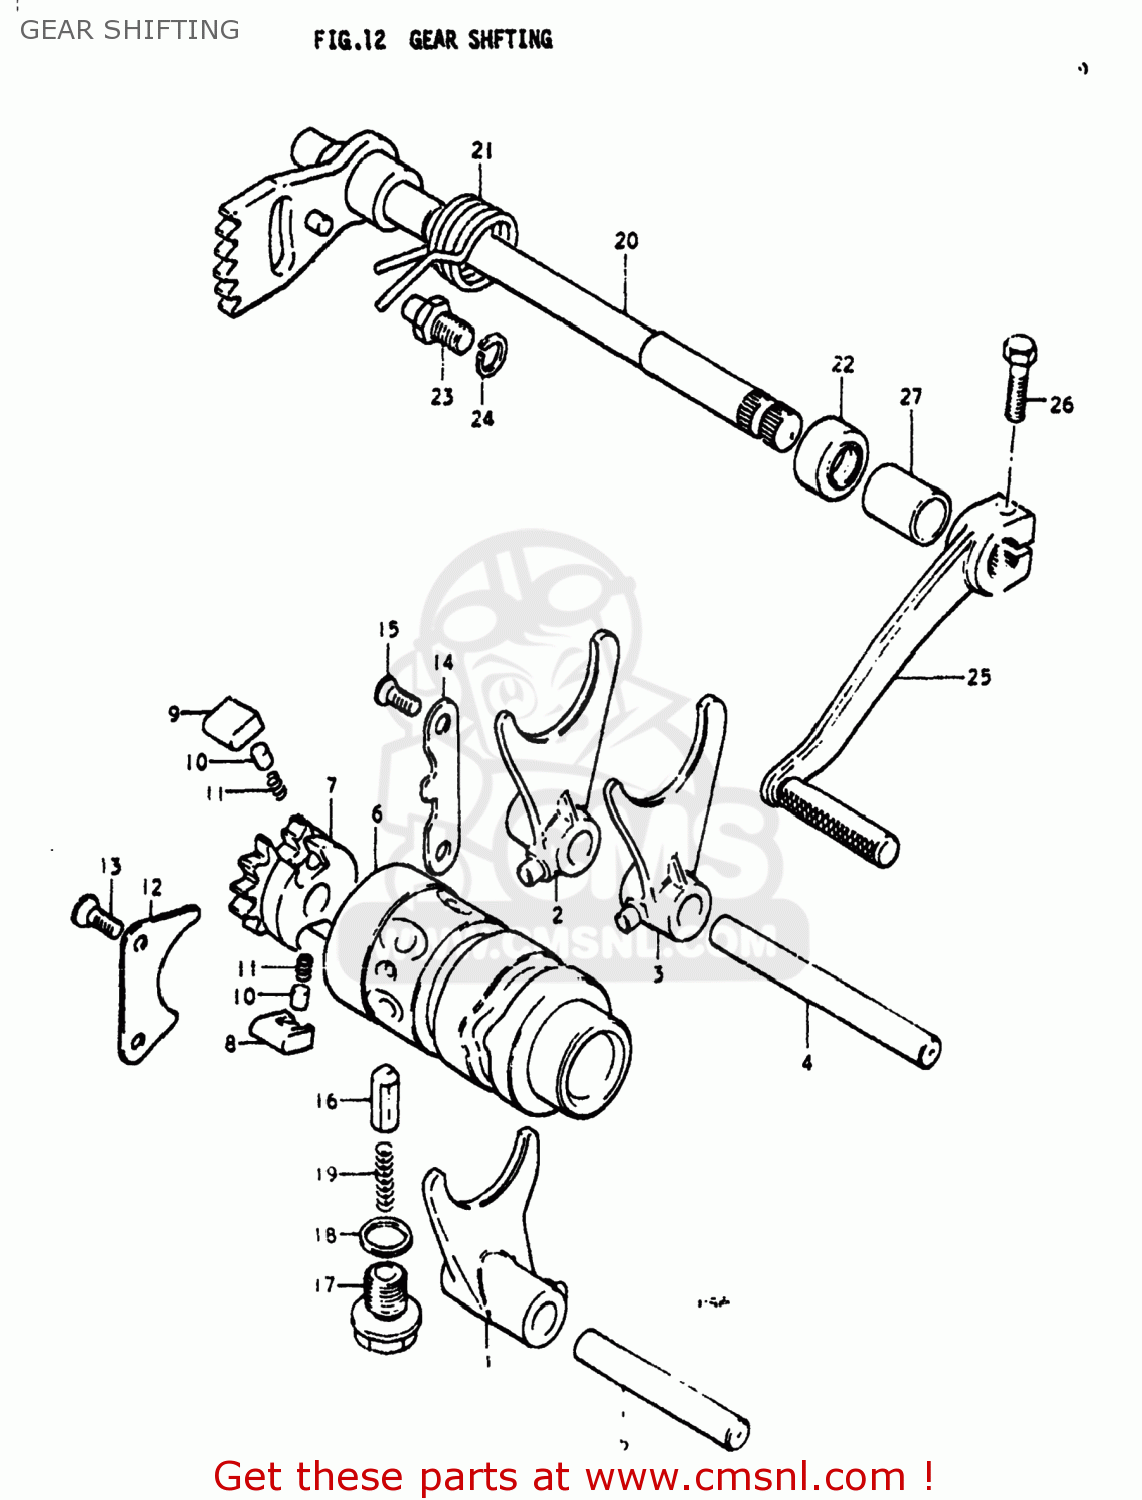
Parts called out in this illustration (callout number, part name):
1	FORK,GEAR SHIFT NO.1
2	FORK,GEAR SHIFT NO.2
3	FORK,GEAR SHIFT NO.3
4	SHAFT,GEAR SHIFT FORK
5	SHAFT,GEAR SHIFT FORK
6	CAM,GEAR SHIFT
7	RETAINER,GEAR SHIFT CAM
8	PAWL,GEAR SHIFT NO.1
9	PAWL,GEAR SHIFT NO.2
10	PIN(5X8)
11	SPRING
12	LIFTER,GEAR SHIFT PAWL
13	SCREW
14	STOPPER,GEAR SHIFT POLE
15	SCREW
16	STOPPER,GEAR SHIFTING
17	BOLT,GEAR SHAFT CAM STOPPER
18	GASKET(14X19.2X2) (NAS)
19	SPRING
20	SHAFT,GEAR SHIFT
21	SPRING
22	OIL SEAL
23	STOPPER,GEAR SHIFT CAM
24	WASHER
25	LEVER ASSEMBLY,GEAR SHIFTING
26	BOLT
27	CUSHION
